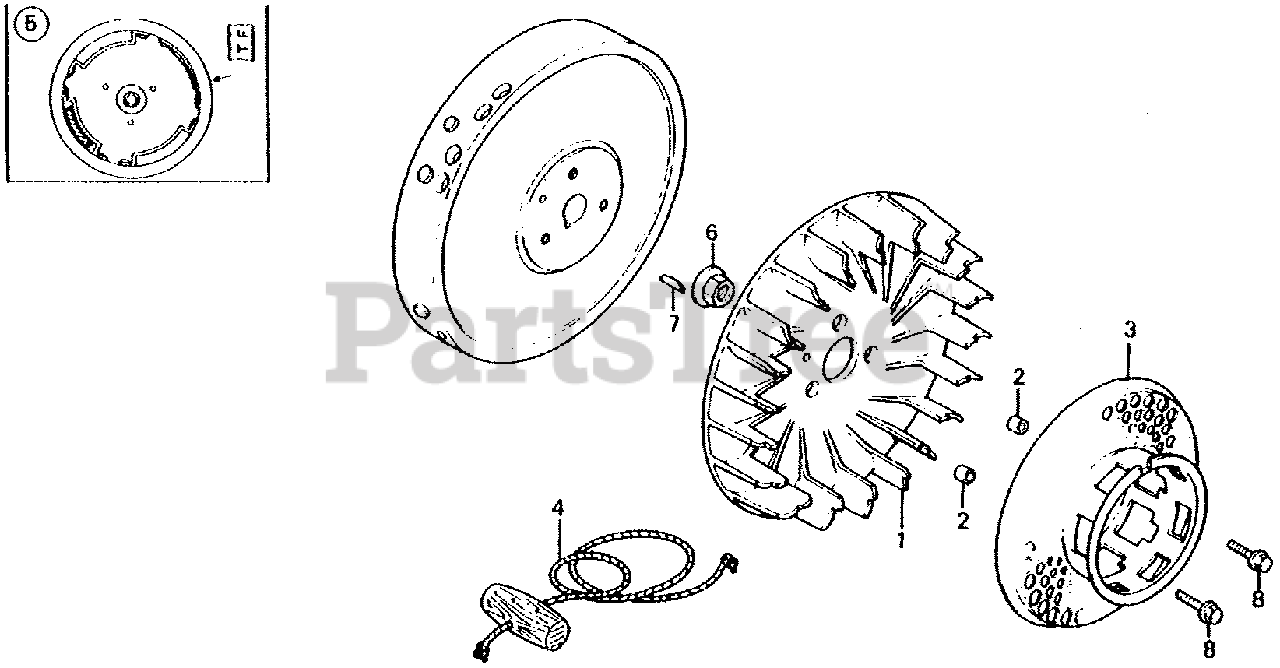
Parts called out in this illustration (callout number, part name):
1	FAN, COOLING
2	COLLAR, FAN
3	PULLEY, STARTER
4	ROPE, STARTER (#5X55")
5	FLYWHEEL
6	NUT, SPECIAL (14MM)
7	KEY, SPECIAL WOODRUFF (25X18)
8	BOLT, FLANGE (6X16)
